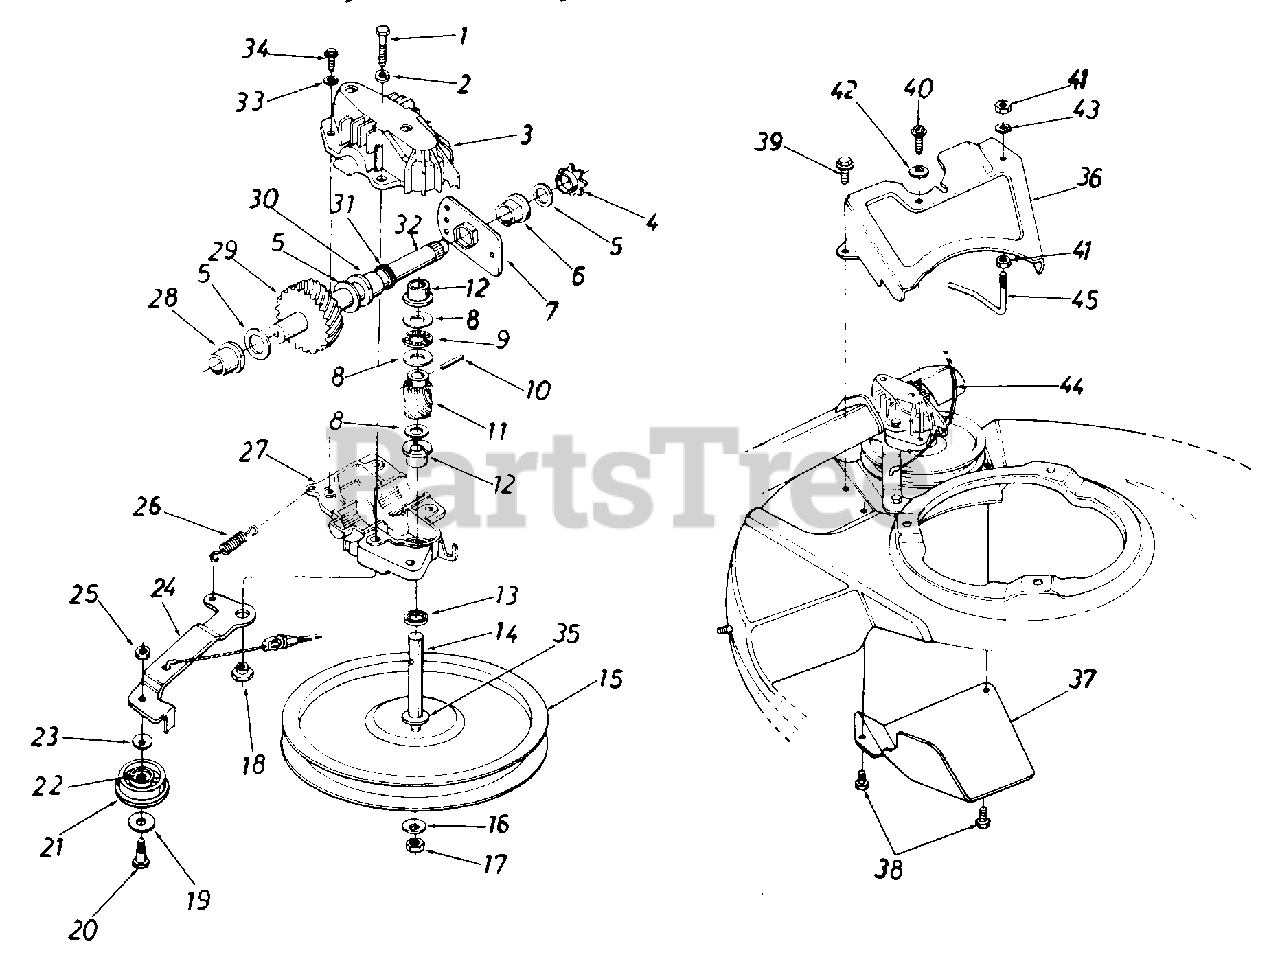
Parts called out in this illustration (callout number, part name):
1	Hex Bolt 1/4-20 x 1.25" Lg.*
2	L-Wash. 1/4" I.D.
3	Upper Hsg. Half
4	#48 Sprocket 7 Tooth x 1/2 Pitch
5	Fl-Wash. 5/8" I.D. x .030
6	Hex Flange Brg. .631" I.D.
7	Hex Bearing Cup
8	Thrust Wash. .382" I.D. x .70" O.D.
9	Thrust Bearing .375" I.D. x .812" O.D.
10	Spring Pin Spir. 1/8" x .62" Heavy
11	11 Tooth Helical Gear
12	Flange Bearing
13	Oil Seal
14	Pulley-Transmission Shaft
15	Fl-Pulley 5.06" I.D.
16	Bell-Wash. .265" I.D. x .75"
17	Hex Nut 1/4-28 L.H. Thd.
18	Shld. Spacer .375" Dia. x .170
19	Fl-Wash. .390" I.D. x 1.0"
20	Shld. Bolt .375" Dia. x .40"
21	Fl-Idler Plastic 1.50" Dia.
22	Needle Brg. .375" x .31"
23	Bell-Wash. .265" I.D. x 75"
24	Idler Brkt Assy.
25	Hex Patch L-Nut 1/4-28 Thd.
26	Extension Spring 1.12" Lg.
27	Lower Hsg. Half
28	Flange Bearing .566 Dia.
29	33 Tooth Helical Gear
30	Flange Bearing .629 Dia.
31	Oil Seal .625 Dia.
32	Gear Sprocket Shaft
33	L-Wash. #10 I.D.
34	Hex B-Tap Scr. #10 x .62"
35	Hex Washer .26" x .88"
36	Transmission Belt Guard
39	Hex AB-Tap Scr. 1/4 x .50" Lg.
40	Hex B-Tap Scr. 1/4 x .62/' Lg.
41	Hex Nut 1/4-20 Thd.
42	Bell-Wash. .265" I.D. x .75"
43	L-Wash. 1/4" I.D.
44	S.P. Cable-48" Lg.
45	S.P. Belt Guard
